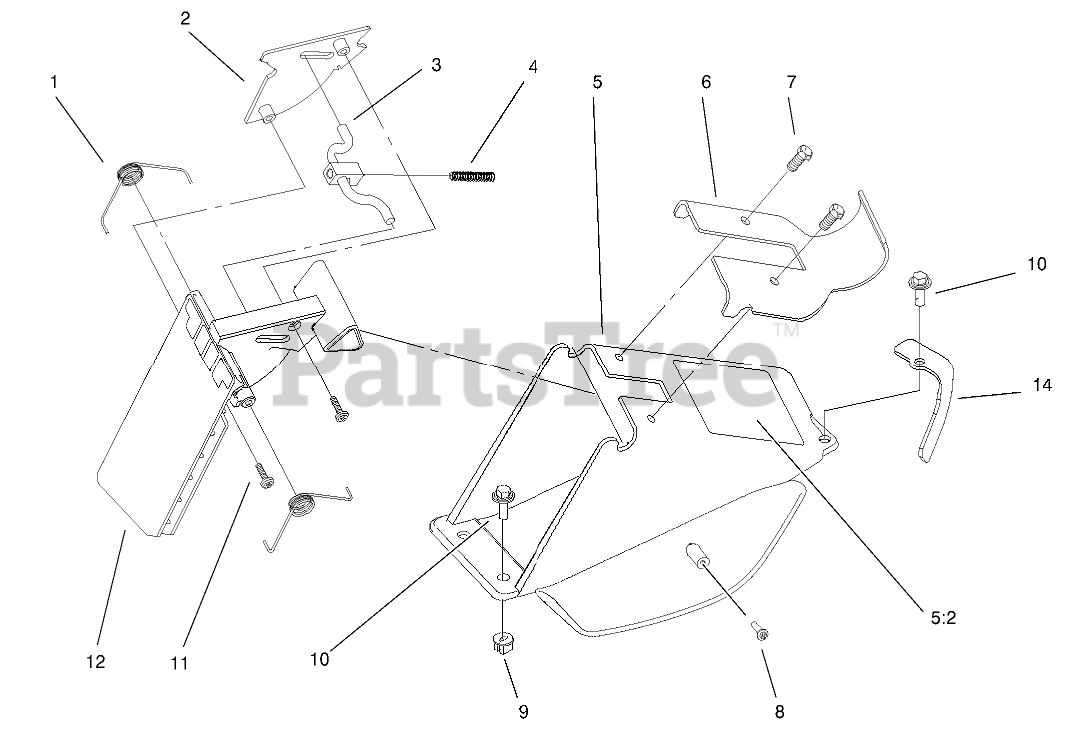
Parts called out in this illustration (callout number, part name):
1	SPRING-DOOR, RH
2	DOOR COVER
3	LATCH-DOOR
4	SPRING-COMPRESSION, LATCH
5	DISCHARGE CHUTE ASM
5:2	DECAL-DANGER
6	Plate-Discharge Chute
7	SCREW-PLASTITE
8	SCREW-PPH
9	NUT - CLIP
10	SCREW-HWH
12	DOOR-DISCHARGE
14	CLAMP-DOOR
